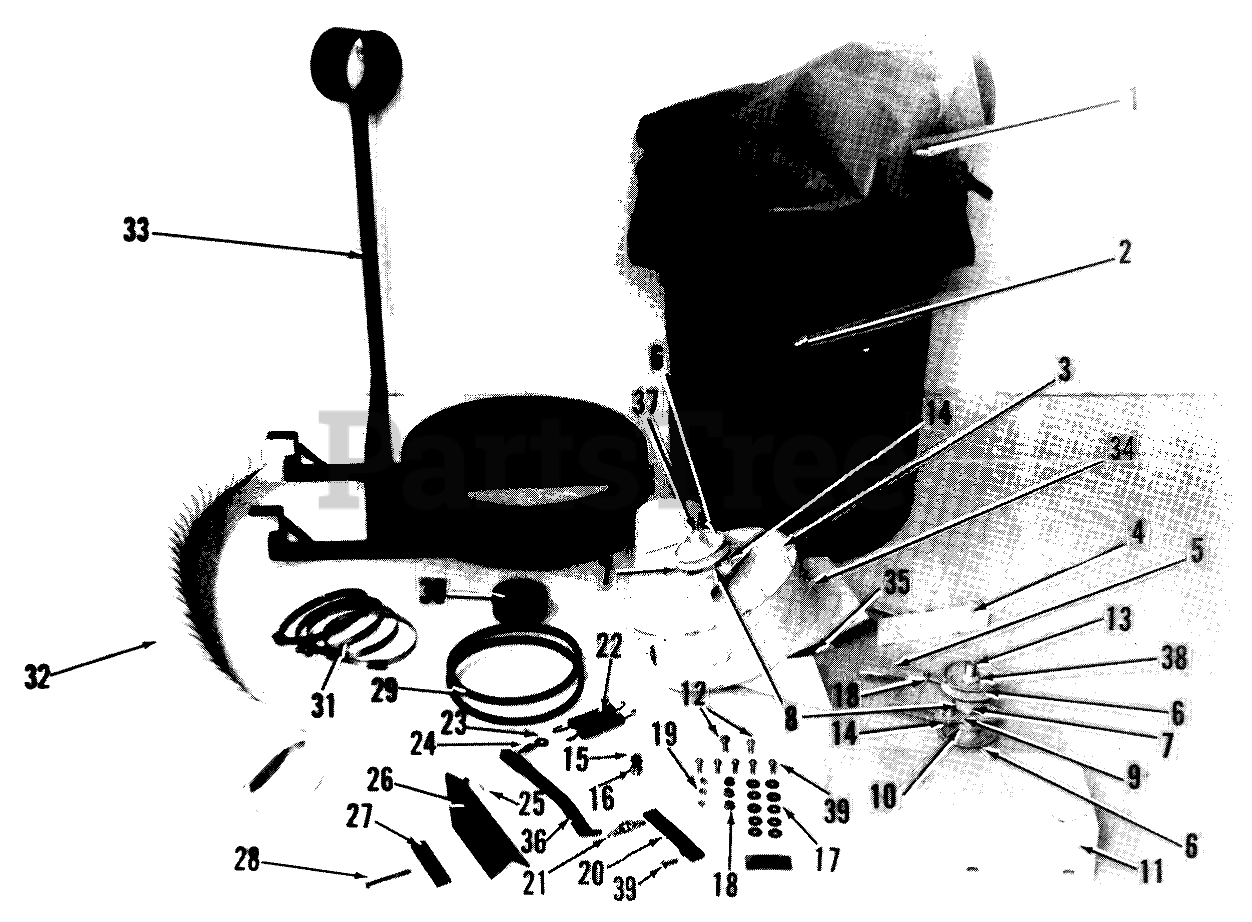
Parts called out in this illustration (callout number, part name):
1	Collector Cover 5.5 Bu Only
2	Collector
3	Blower Top
4	Blower Inlet Deflector
5	Strap
6	PULLEY
7	Spacer
8	Drive Hub
9	Drive Bracket
10	Bearing
11	Belt Cover
12	Bolt
13	Bolt 3/4-16 x 6
14	Bolt
15	Hhcs
16	Eslok Nut
17	Washer
18	NUT
19	Flanged Nut
20	Stabilizer Adjustment Bracket
21	Chain
22	SPRING TENSION
23	Eye Bolt
24	Nut
25	Hairpin Cotter
26	Pivot Bracket
27	Pivot Bracket Support Bar
28	Screw-Hex. Hd.
29	BELT-BLOWER DRIVE
30	Sheave-2 Groove
31	Hose Clamps
32	Discharge Tube
33	Collector Barrel Mounting Bracket 5.5 Bu Only
33	Collector Barrel Mounting Bracket 6.7 Bu Only
34	Blower Welded Bottom
35	IMPELLER BLOWER
36	Pivot Arm
37	BOLT HEX 3/4-16X61/2
38	Nut
39	Bolt
